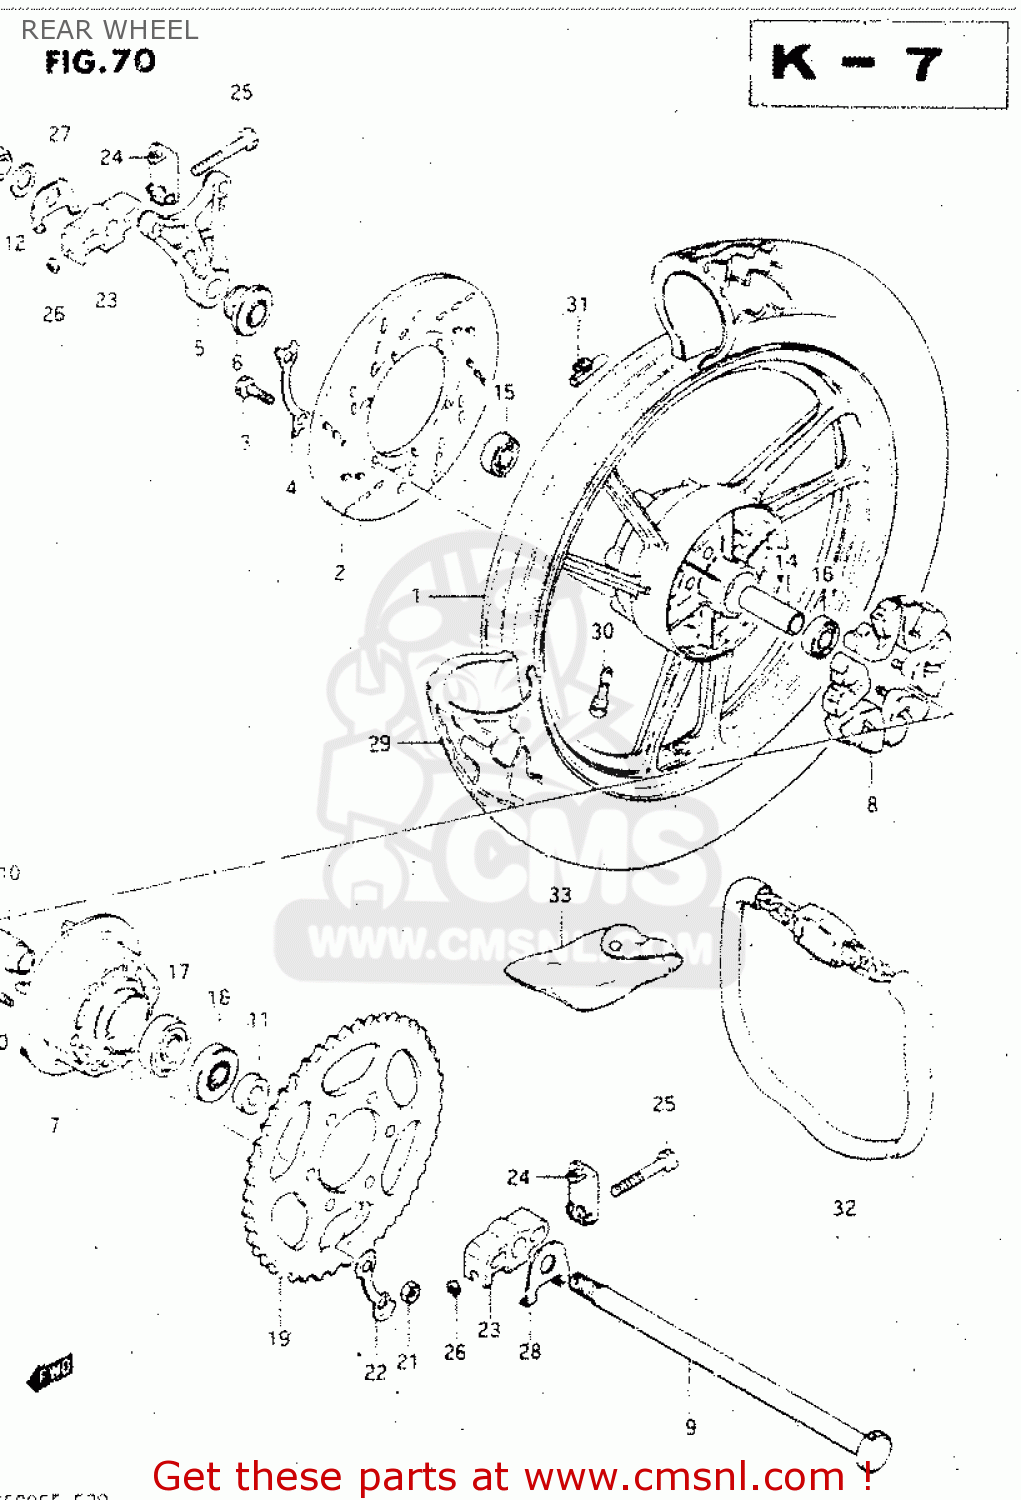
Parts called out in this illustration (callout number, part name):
1	WHEEL,REAR
2	DISC,REAR BRAKE
3	BOLT(8X25)
4	WASHER
5	BRACKET,RR,CALIPER
6	SPACER,REAR AXLE
7	DRUM,REAR SPROCKET MOUNT
8	ABSORBER,RR HUB SHOCK
9	AXLE,REAR
10	SPACER,REAR HUB BEARING
11	SPACER (17X30.5X13.5)
12	WASHER
13	NUT
14	SPACER(17.5X25X81)
15	BEARING
16	BEARING
17	BEARING
18	SEAL,OIL(30.5X52X8)
19	SPROCKET,RR
20	BOLT(10X35.5)
21	NUT
22	WASHER
23	BODY,CHAIN ADJUSTER
24	PLATE,CHAIN ADJUSTER
25	BOLT,CHAIN ADJUSTER
26	E RING
27	WASHER,CHAIN ADJUSTER RH
28	WASHER,CHAIN ADJUSTER
29	TIRE
30	VALVE,TIRE
31	BALANCER,WHEEL
32	CHAIN LOCK ASSY
33	BAG,CHAIN LOCK
